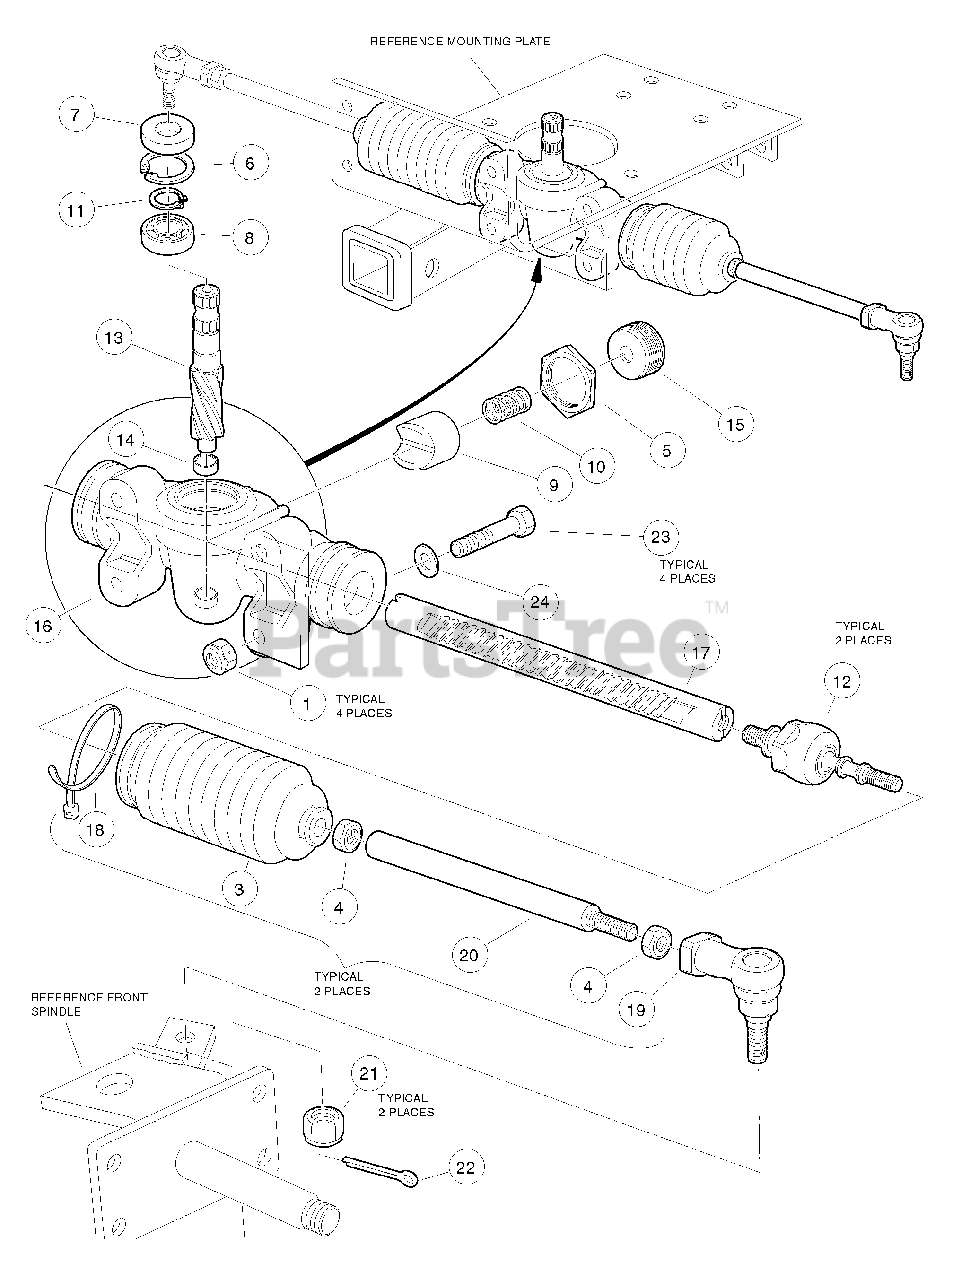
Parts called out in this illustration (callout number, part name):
1	Locknut, 3/8-16 Dimpled
2	Rack and Pinion Steering Gear
3	Bellows, Long
4	Nut, 12mm Hex
5	Rack Screw Locknut
7	Seal, Steering Pinion Dust
8	Bearing, Ball
9	Support Yoke
10	Rack Guide Pressure Spring
11	Ring, Stop, C-Type
12	Inner Ball Joint Asm
13	Pinion, Steering
14	Bearing, Lower Pinion
15	Screw, Rack Guide
16	Housing, Steering Gear
17	Rack, Steering
18	Tie Wrap, 8" Nylon
19	End, Tie Rod M12 X 1.25
21	Locknut, M12-1.25 Nylon
22	Pin, Cotter
23	Screw, 3/8-16 X 1.50 Hex-Head Cap
24	Washer, 3/8 Type A Flat
